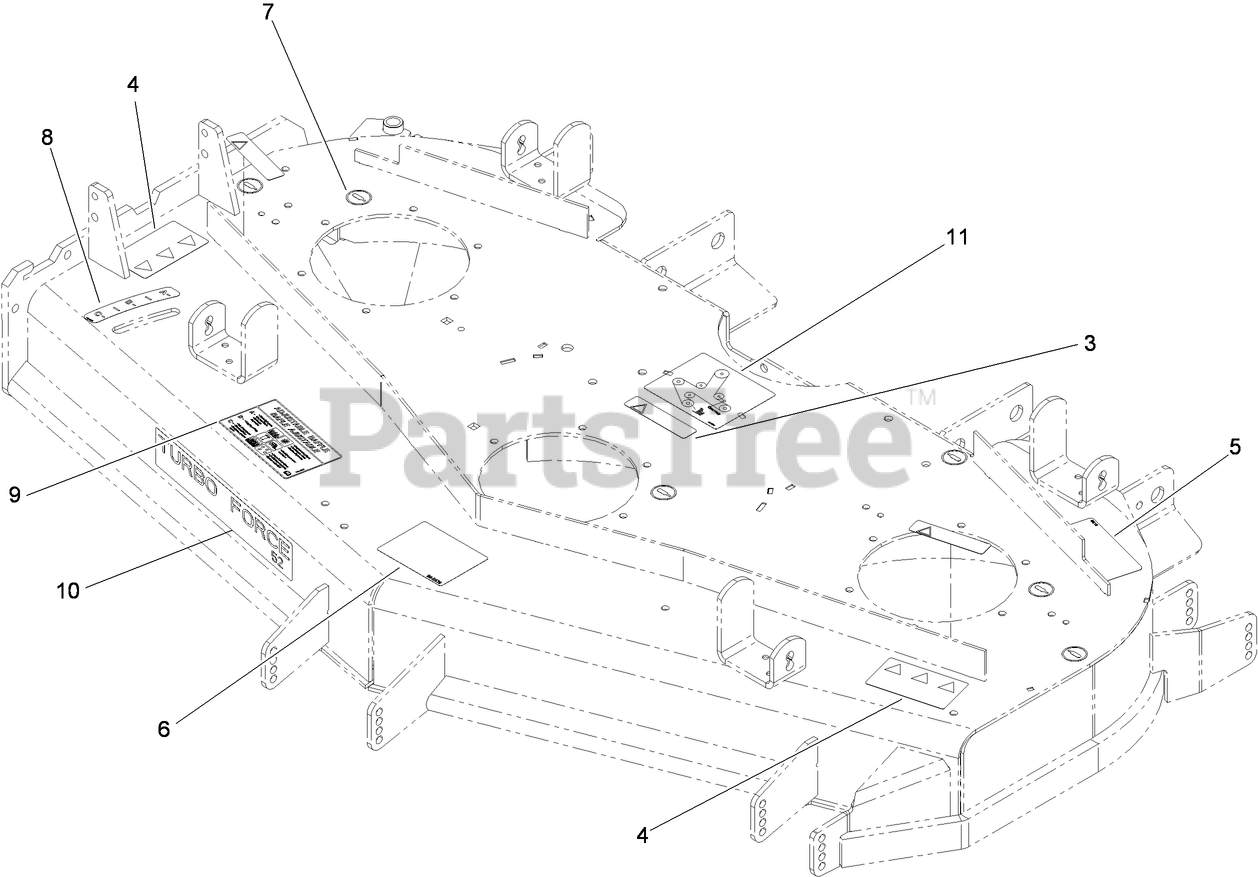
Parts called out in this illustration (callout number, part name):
3	DECAL-WARNING
4	DECAL-DANGER
5	DECAL-TORQUE, BLADE BOLT
6	DECAL-ANTI SCALP
7	DECAL-GREASE
8	DECAL-SETTING, BAFFLE
9	DECAL-ADJUSTMENT, BAFFLE
11	DECAL-ROUTING, BELT
